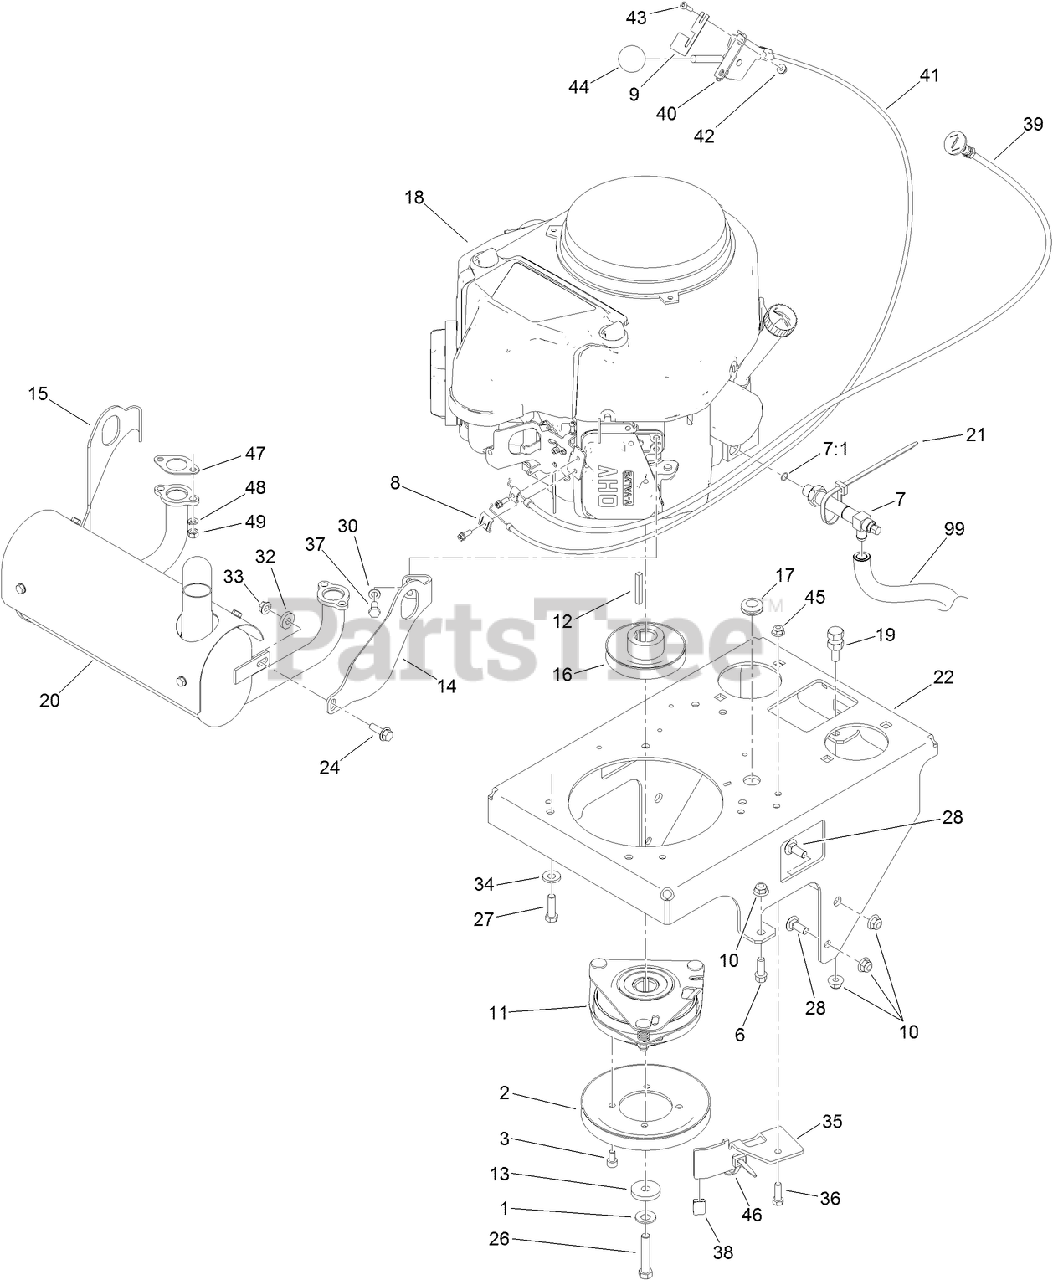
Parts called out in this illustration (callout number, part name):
1	WASHER-SPRING
2	PULLEY
3	SCREW-HSH
7	DRAIN-OIL, VALVE, KAW
7:1	O-RING
8	CLAMP-CABLE
9	PLATE-SET, THROTTLE
10	NUT-HF, NI
11	CLUTCH/BRAKE ASM
12	KEY-SQUARE
13	WASHER
14	BRACKET-MUFFLER MOUNT, LH
15	BRACKET-MUFFLER MOUNT, RH
16	PULLEY
17	GROMMET
19	ANCHOR-SPRING, SHORT
20	MUFFLER
21	TIE-CABLE
22	BASE-ENGINE
24	SCREW-HHF
26	SCREW-HH
27	SCREW-HH
28	BOLT-CARR
30	WASHER-LOCK
32	SPACER
33	NUT-HF
34	WASHER-BELLEVILLE
35	BRACKET-CLUTCH STOP
36	SCREW-HH
37	SCREW-HH
38	BUMPER
39	CONTROL-CHOKE, PUSH / PULL
40	LEVER-CONTROL
41	CABLE-CONTROL
42	NUT-LOCK, FLANGE
43	SCREW-TORX
44	KNOB-BALL
45	NUT-HF, NI
46	TIE-CABLE
47	GASKET-EXHAUST
48	WASHER-LOCK
99	HOSE-DRAIN, OIL
